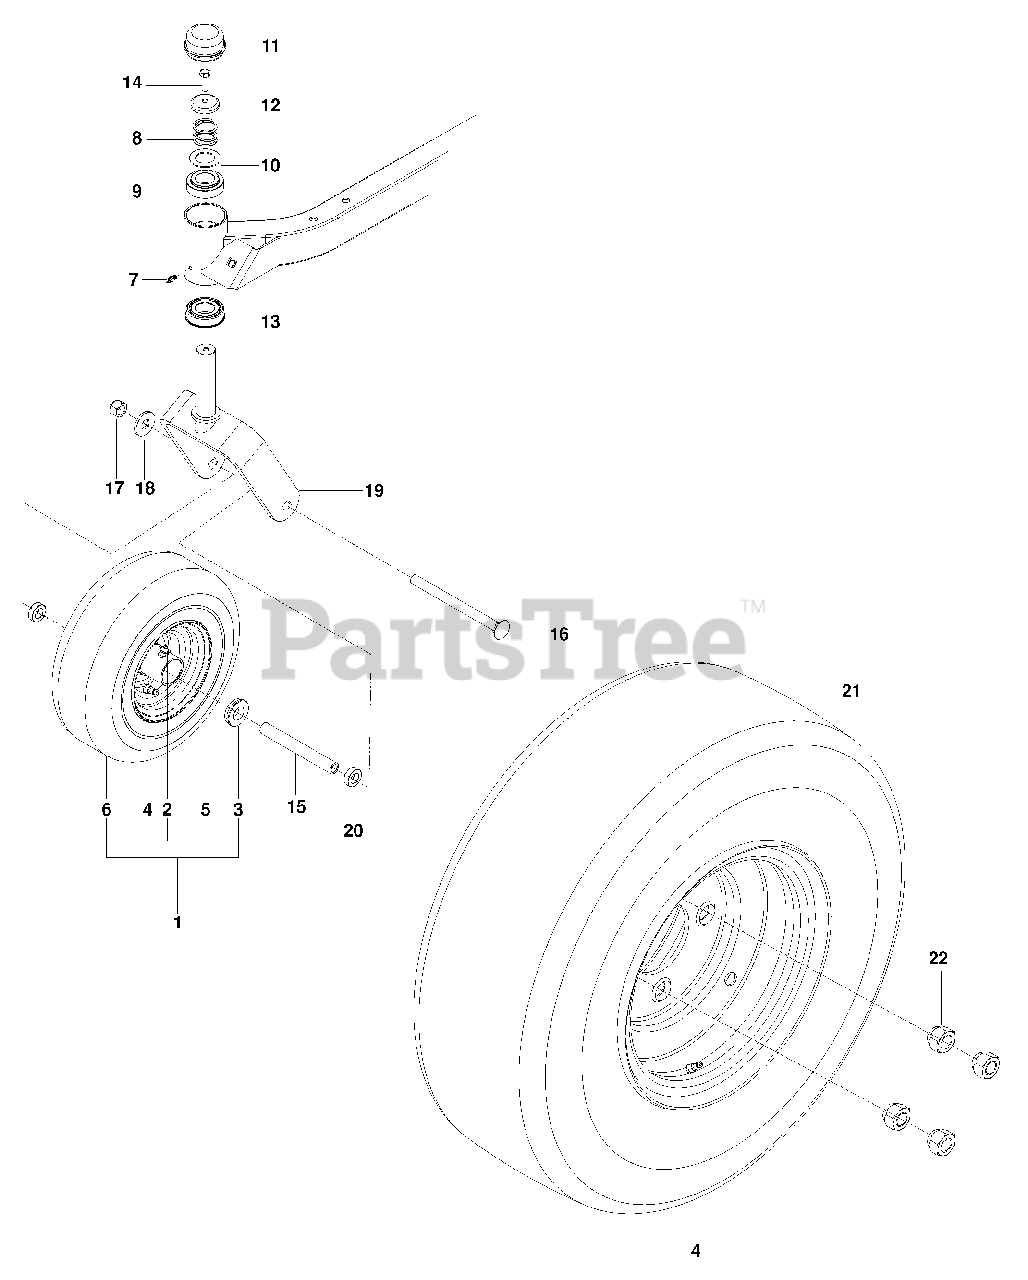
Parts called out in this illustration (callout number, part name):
1	CASTER TIRE ASSY
2	ZERK
3	BEARING, FLANGED
7	ZERK
8	SPRING, CASTER
9	BUSHING, CASTER
11	CAP, GREASE
12	PLUG, CASTER
13	BEARING, FLANGED
14	HHB 5/16-18 x 1 NYLOC
16	RHSNB 1/2-13 x 6 1/2
17	NUT 1/2 HEX NYLOC
18	WASHER 1/2 FLT
19	YOKE, CASTER ORG
20	SPACER 5/16
21	WHEEL ASSY REAR
22	NUT 1/2 LUG
